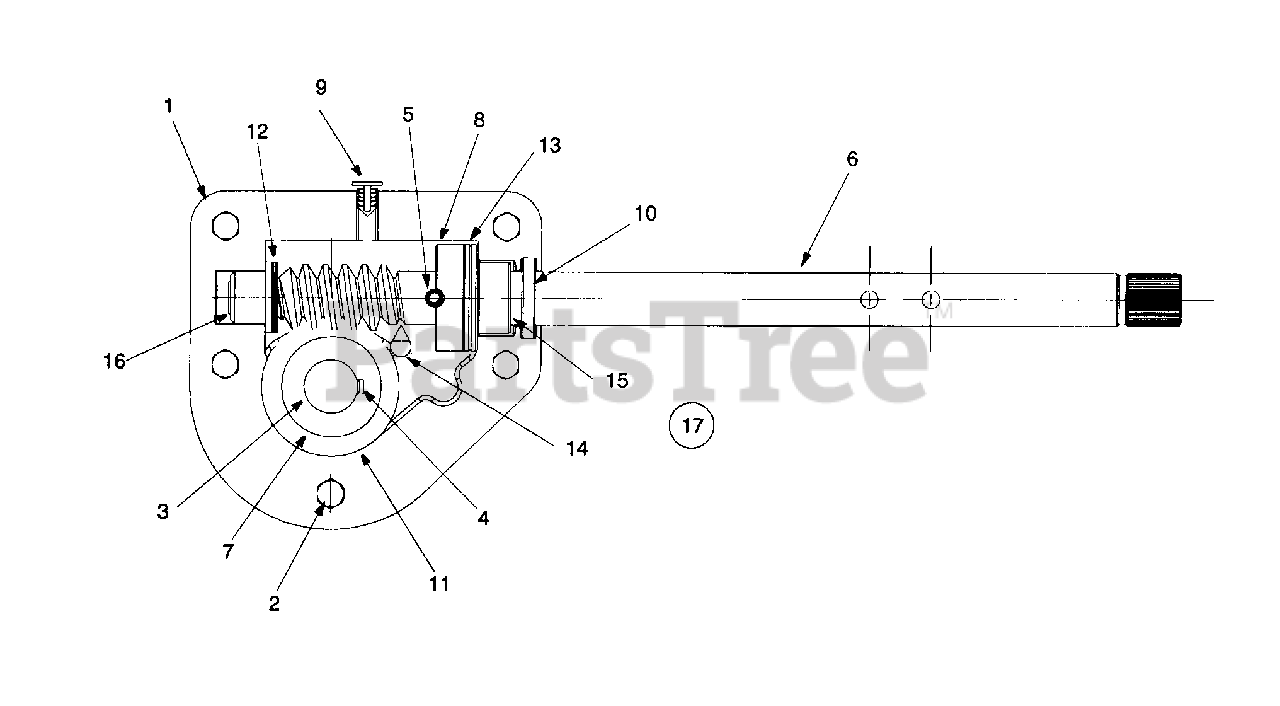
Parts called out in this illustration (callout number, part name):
1	Housing - L.H.
2	Hex Screw 1/4-20 x .75
3	Spiral Axle 24"
4	Key
6	Shaft-Worm
7	Gear-Worm
8	Collar-Thrust
14	Grease, 1.5 oz Alvania EP Lead Free
15	Bearing-Flange
16	Bearing-Flange
17	Gear Case Complete, 24"
